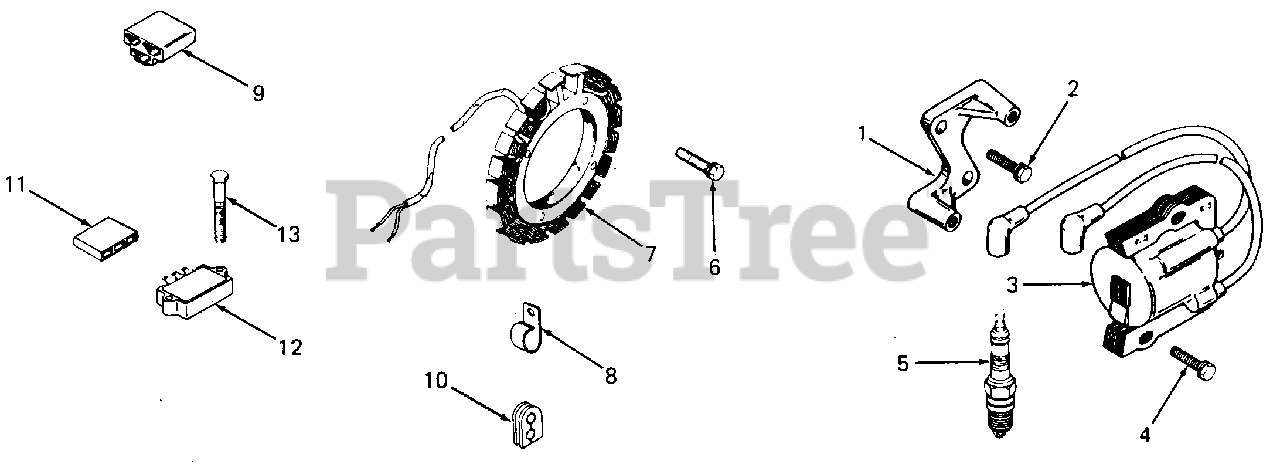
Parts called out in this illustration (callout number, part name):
1	Bracket, Module
2	Screw, Hex Wash Hd, 1/4-20 X 7/8 Lg
3	Module, Ignition
4	Screw, Hex Wash Hd, 1/4-20 X 1.0 Lg
5	Spark Plug
6	Screw, Hex Wash Hd, #10-24 X .75 Lg
7	Kit, Stator
11	Connector, Rectifier-Regulator
12	Rectifier-Regulator
13	Screw, Hex Cap, 1/4-20 X 7/8 Lg
